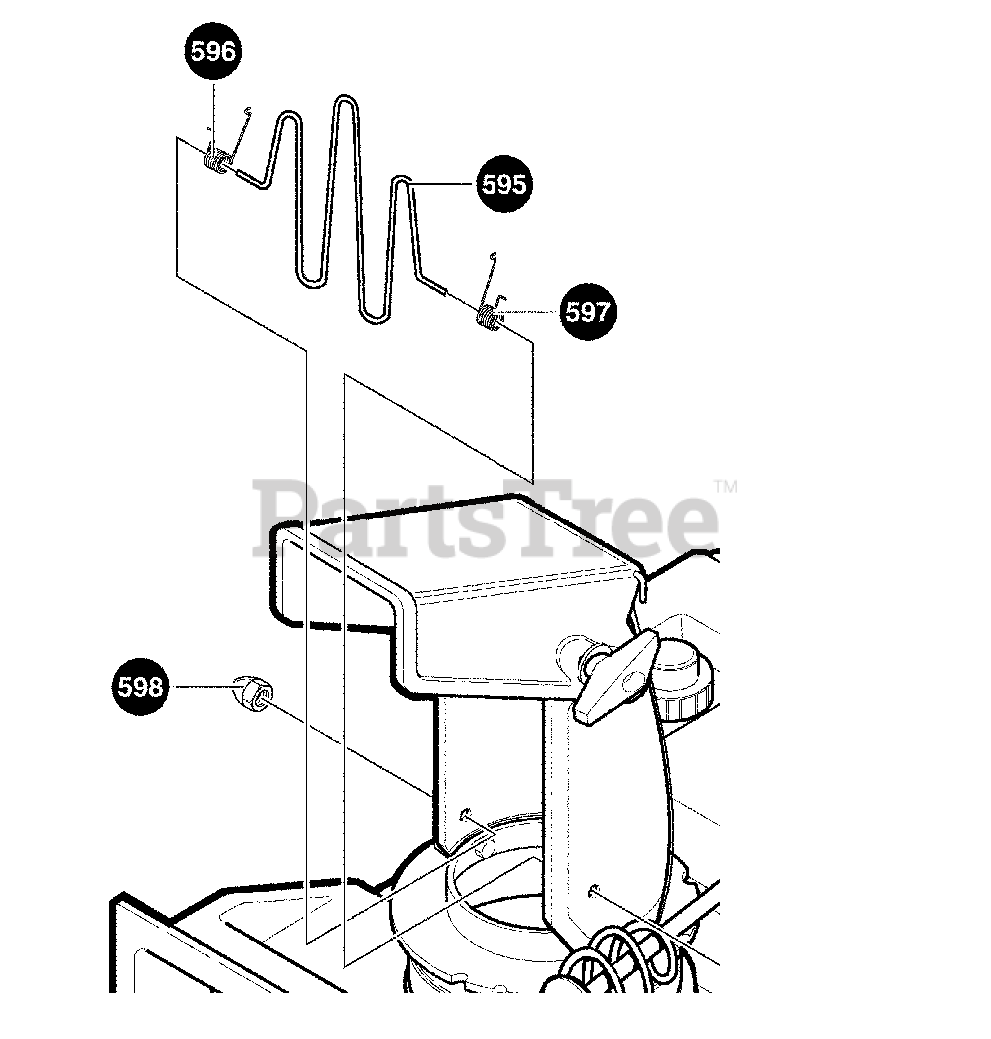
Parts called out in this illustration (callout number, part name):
595	GUARD, WIRE CHUTE
596	SPRING, TORSION
597	SPRING, TORSION
598	NUT, ACORN
